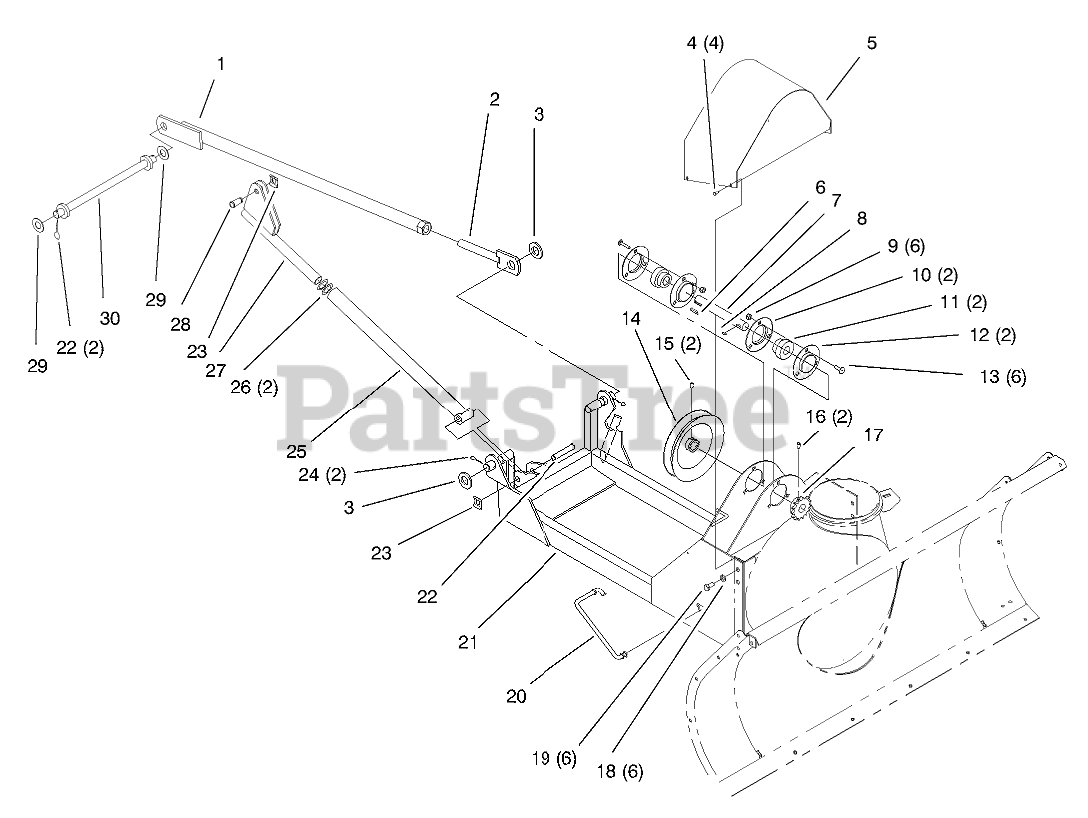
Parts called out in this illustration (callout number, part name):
1	Brace-Wa
2	Adjuster Wa
3	WASHER-FLAT
4	SCREW-SHH
5	Cover-Pulley
6	KEY
7	SHAFT - JACK
8	KEY-HI PRO
9	NUT-LOCK, NI
10	FLANGETTE - BEARING
11	BEARING AND COLLAR
12	FLANGETTE - BEARING
13	BOLT-CARR
14	PULLEY-DRIVE
15	SCREW-SQH
16	SCREW-SET, SQH
17	SPROCKET-15 T
18	WASHER-LOCK
19	SCREW-HH
20	LINK - SPRING TENSION
21	Frame-Wa
22	PIN-CLEVIS
23	CLIP-PIN
24	PIN-HAIR
25	Rod-Lift
26	WASHER-FLAT
27	Yoke-Wa
28	PIN-CLEVIS
29	WASHER-FLAT
30	Link-Wa
